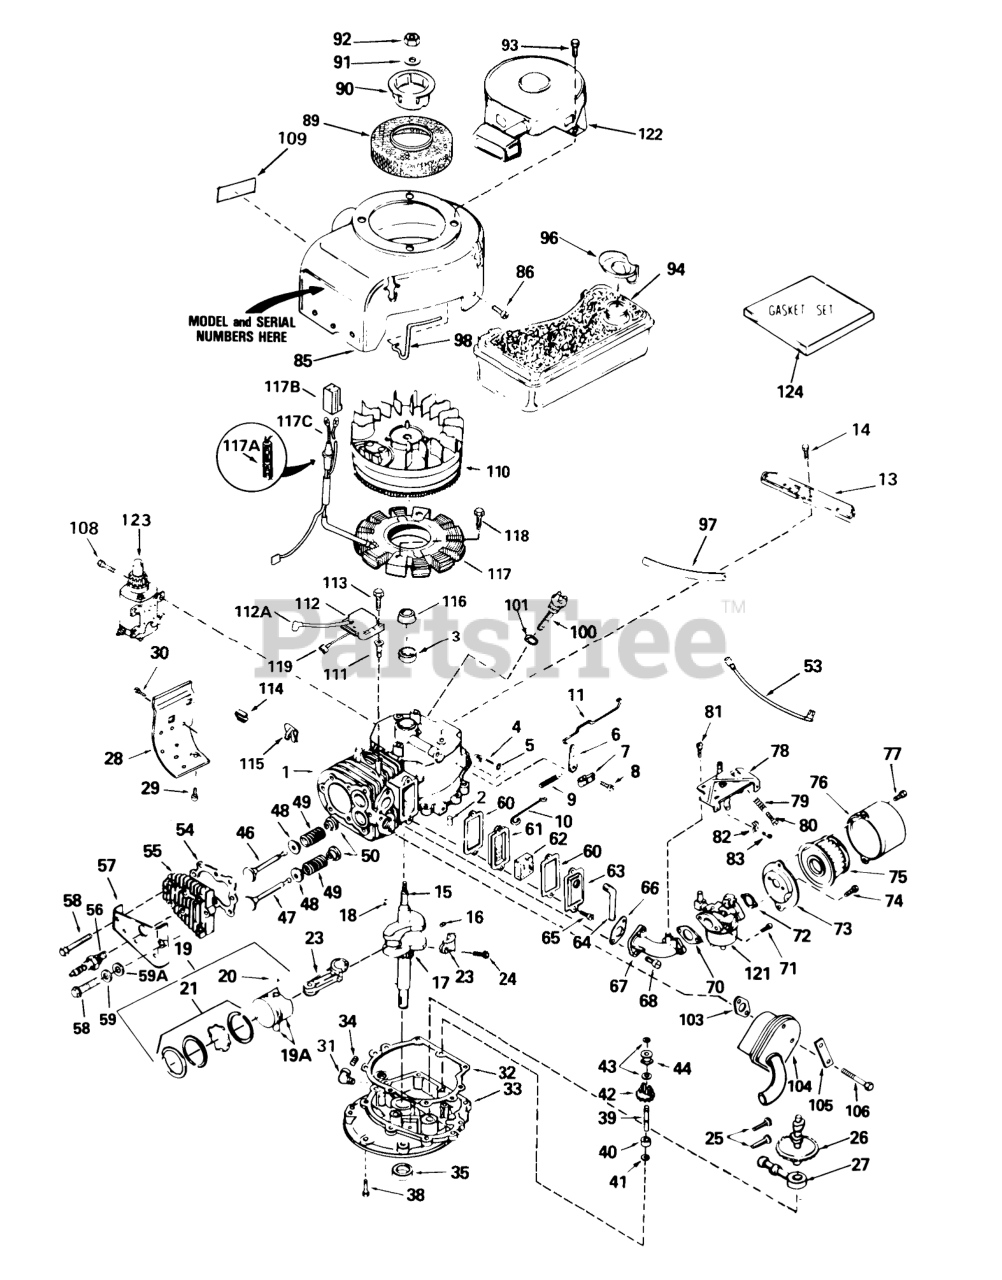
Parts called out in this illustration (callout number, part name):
1	Cylinder Assembly (Incl. #2, 3, 100 & 101)
2	Pin-Dowel
3	Oil Seal
4	Rod-Governor (Incl. #5)
5	Washer-Flat
6	Lever-Governor
7	Clamp-Lever, Governor
8	Screw
9	Spring Governor
10	Link Governor Spring
11	Link Governor
13	Bracket-Blower Housing
14	Screw (1/4-20x19/32)
15	Crankshaft Assembly (Incl. #16 & 17)
16	Pin, Groove
17	Gear-Crankshaft
18	Key-Flywheel
19	Piston-Pin & Ring Assembly (Std.) (Incl. #19A, 20 & 21)
19	Piston-Pin & Ring Assembly (.010 oversize) (Incl. #19A, 20 & 21)
19	Piston-Pin & Ring Assembly (.020 oversize) (Incl. #19A, 20 & 21)
19A	Piston & Pin Assembly (Std.) (Incl. #20)
19A	Piston & Pin Assembly (.010 oversize) (Incl. #20)
19A	Piston & Pin Assembly (.020 oversize) (Incl. #20)
20	Ring-Retaining, Piston Pin
21	"O"Ring
21	Ring Set (.010" OS)
21	Ring Set (.020" OS)
23	Rod Assembly-Connecting (Incl. #24)
24	Bolt-Connecting Rod
25	Lifter-Valve
27	Pump, Oil
28	Extension-Blower Hsng.
30	Screw
31	Street Elbow (90 degrees) (Can be purchased locally)
32	Gasket-Cover, Cylinder
33	Flange Assembly-Mounting (Incl. #34, 35, 39 & 41)
34	Plug-Drain, Oil (SQH 1/4-18)
35	Seal-Oil
38	Screw (1/4-20 x 1-1/4)
39	Shaft, Governor
40	Spacer Assembly-Governor (Incl. #41)
41	Washer-Flat
42	Gear Assembly-Governor (Incl. #41)
43	Ring-Retaining
44	Spool-Governor
46	Valve-Intake (Std.) (Incl. #50)
46	Valve-Intake (1/32" oversize) (Incl. #50)
47	Valve-Exhaust (Std.) (Incl. #50)
47	Valve-Exhaust (1/32" oversize) (Incl. #50)
48	Cap-Spring, Valve
49	Spring-Valve
50	Keeper-Spring, Valve
53	Wire-Ground
54	Gasket-Cylinder Head
55	Head-Cylinder (Incl. 3 of #58)
56	Plug, Spark (Champion RCJ-8)
57	Cover-Head, Cylinder
58	Screw (5/16-18 X 2-1/2)
59	Washer-Belleville
59A	Washer-Flat
60	Gasket-Breather
61	Body-Breather
62	Element-Breather
63	Cover-Valve
64	Tube-Breather
66	Gasket-Intake
67	Pipe-Intake
68	Screw (T-30, 5/16-18x1-3/32)
70	Gasket
71	Screw-Hex Hd.
72	Gasket
73	Bracket
74	Screw (10-32 x 1/2)
75	Element
76	Body-Air Cleaner
78	Control Assembly-Speed (Incl. #79 & 80)
79	Spring-Compression
80	Screw
81	Screw (10-24 x 9/16)
82	Conduit
83	Screw (10-32 x 3/8)
85	Housing-Blower
89	Screen-Starter
90	Cup-Starter
91	Washer-Belleville
94	Tank Assembly-Fuel
96	Deflector-Fuel
97	Line-Fuel (8.62)
98	Clamp, Tank Holdown
100	Dipstick-Oil (Incl. #101)
101	Gasket
103	Gasket Exhaust
104	Muffler
105	Plate-Locking
106	Screw Hex Hd.
108	Screw
109	Decal-Instruction
110	Flywheel (3 Amp, with Ring Gear)
111	Stud
112	Solid State
112A	Cover-Spark Plug
113	Screw
114	Clip, Spring
115	51004 GIL ROTARY TI
116	Spacer-Coil
117	Coil Assembly-3 Amp D.C. (Incl. #117A, 117B & 117C)
117A	Diode
117B	Connector Body
117C	Terminal-Female
118	Screw (1/4-20 x 3/4)
119	Terminal
121	Carburetor (Incl. #70)
122	tarter-Rewind
123	Tine Shaft
124	Gasket Set
